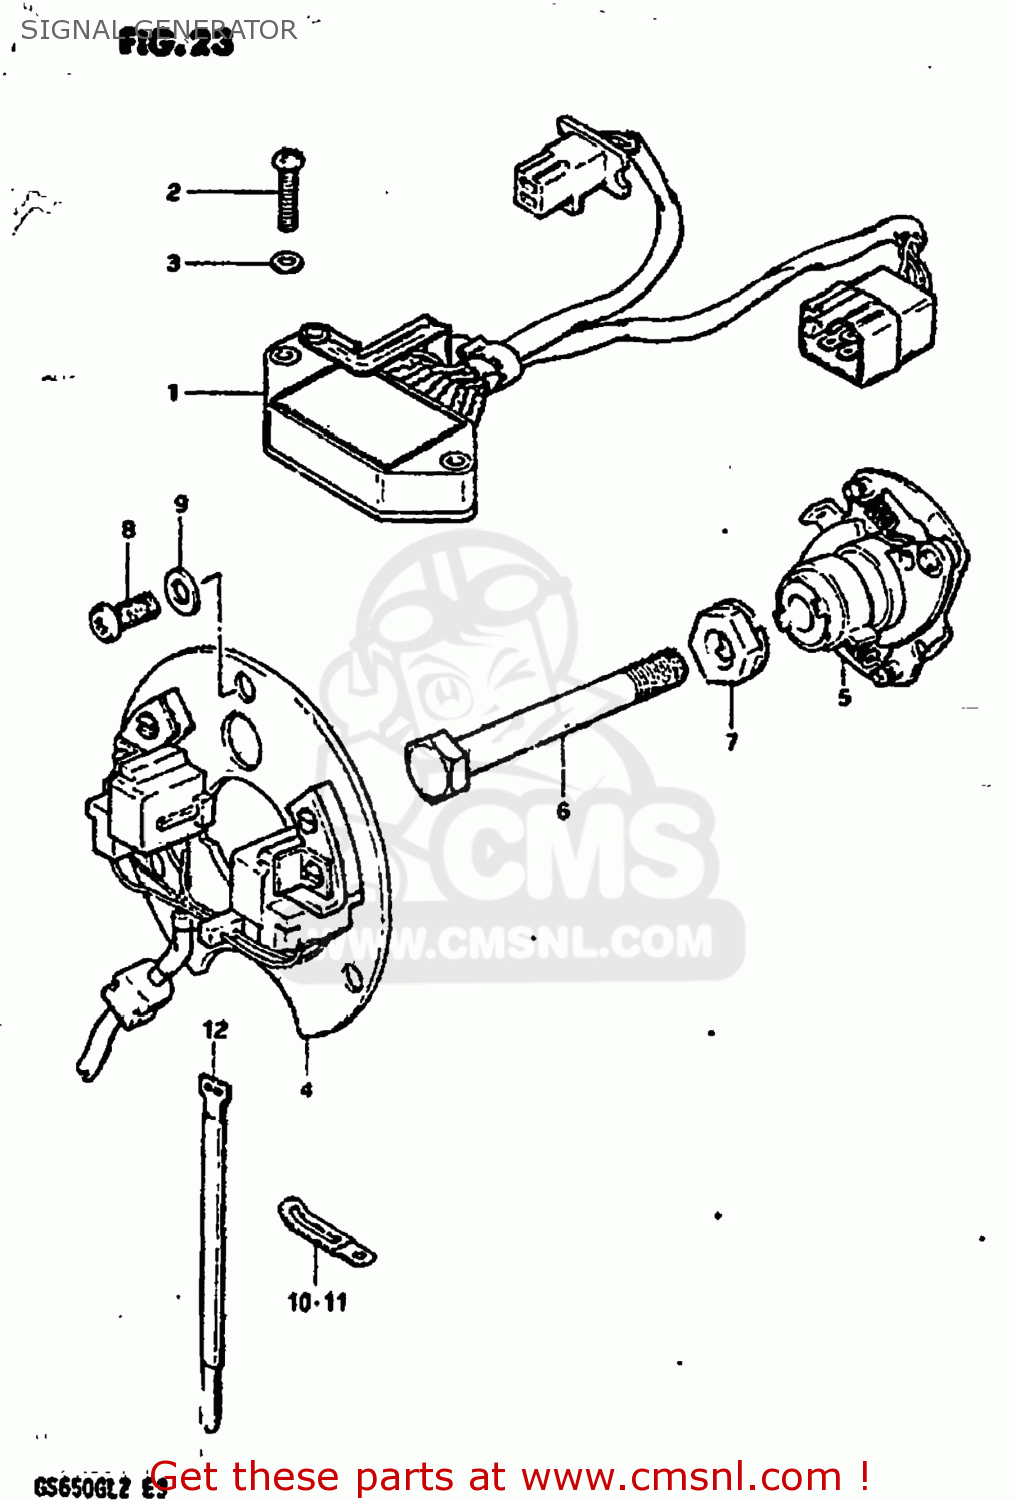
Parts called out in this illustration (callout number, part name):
1	IGNITER UNIT ASSEMBLY
2	SCREW
3	WASHER
4	SIGNAL GENERATOR ASSEMBLY
5	GOVERNOR ASSEMBLY
6	BOLT
7	WASHER
8	SCREW(5X12)
9	WASHER
10	CLAMP L:35
11	CLAMP
12	CLAMP
